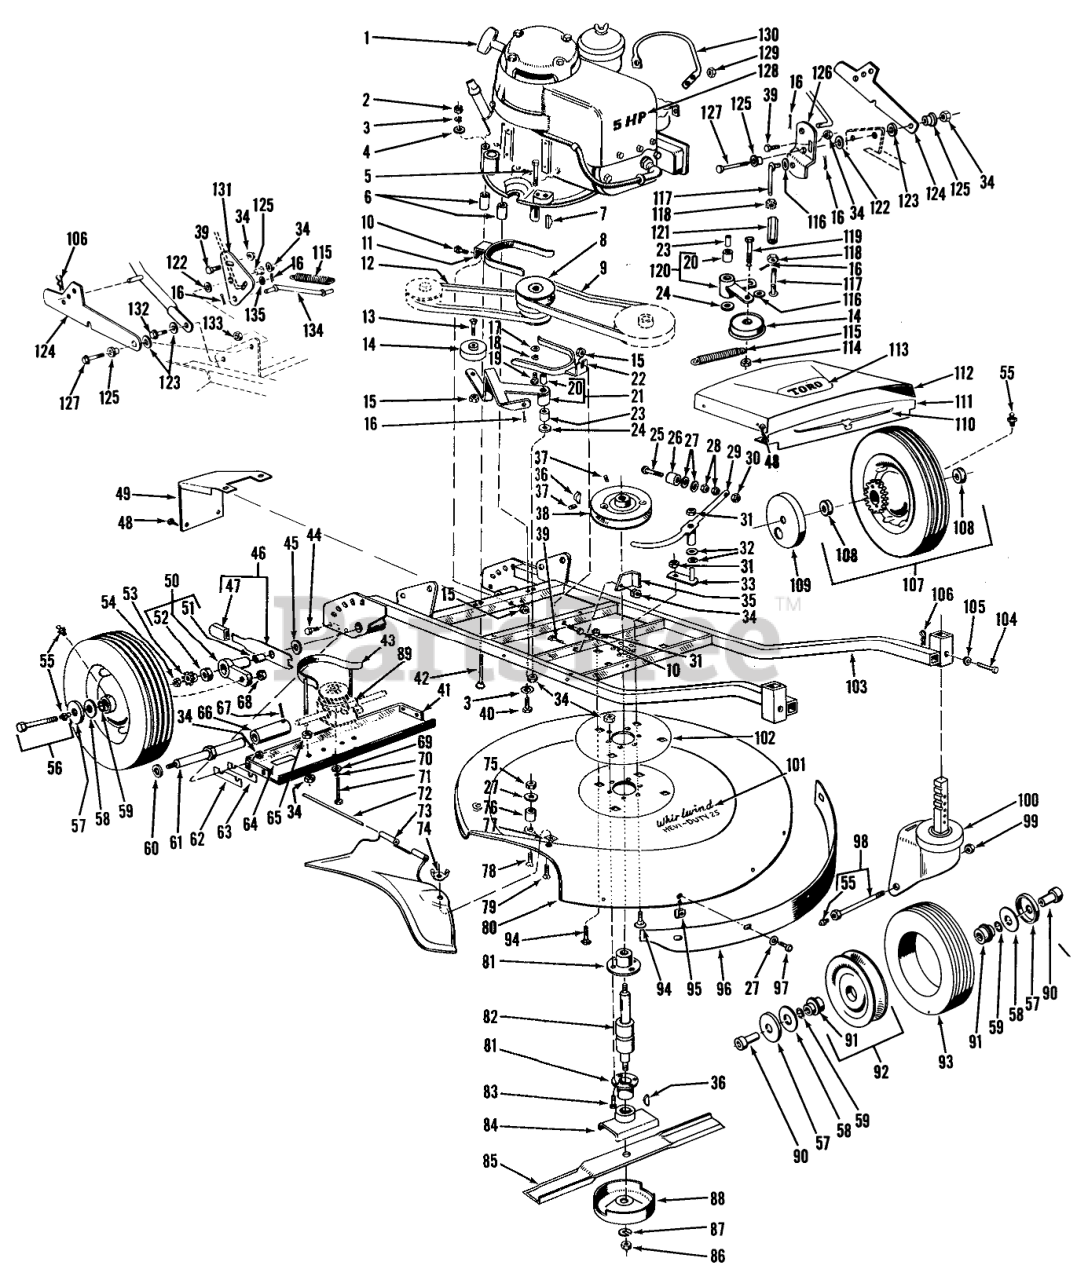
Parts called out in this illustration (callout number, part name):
1	Engine
2	NUT-HEX
3	WASHER-LOCK
4	WASHER-PLAIN
5	SCREW-HH
6	Spacer
7	KEY-WOODRUFF
8	Pulley
9	CUTTER BELT
10	SCREW-HH
11	Retainer, Belt
13	Flat Head Screw
14	PULLEY B
15	NUT-LOCK, NI
16	PIN-COTTER
17	WASHER-FLAT
18	WASHER-LOCK
19	SCREW-HH
20	BUSHING
21	Idler Arm
22	Retainer Belt
23	ENGINE PIVOT SPACER
24	SPACER
25	10-24X1-1/2 RND HD MS
26	BUMPER
27	WASHER-FLAT
28	NUT-HEX
29	Arm, Brake
30	NUT-LOCK, NI
31	NUT-LOCK, NI
32	WASHER-FLAT
33	Base Pivot
34	NUT-LOCK, NI
35	Belt Retainer
36	KEY-WOODRUFF
37	SCREW-HSH
38	CUTTER PULLEY
39	SCREW-HH
40	SCREW-HH
41	Support
42	Screw, Truss Head
43	Belt Band
44	SCREW-HH
45	WASHER
46	Spring Arm
48	10-16 X 3/8 THDG SCREW
49	Rear Shroud
50	Pivot Arm
51	.375 RPP BALL BEARING
52	BUSHING
53	Pinion Kit
54	NUT-HJ
55	FITTING-GREASE
56	Axle Bolt Use on Serial No. 1 thru 250
57	SLINGER
58	Washer
59	O-RING
60	Washer
61	Drive Spindle
62	Shim .015
63	Shim .030
64	Serial & Patent No. Decal
65	NUT-JAM
66	Clutch Assembly
67	Groove Pin
68	NUT-LOCK, NI
69	WASHER-FLAT
70	WASHER-LOCK
71	SCREW-HH
72	Hinge Pin
73	DEFLECTOR
74	Nut Wing
75	NUT-HEX
76	Spacer
77	Nut, Speed
78	Screw
79	5/16-18X7/8 FLT HD MS
80	Housing
81	BEARING HOUSING
82	Bearing Spindle
83	SCREW-HH
84	Retainer
85	Blade
86	NUT-HEX
87	WASHER-LOCK
89	Transmission Assembly
90	Spacer
91	BEARING-BALL
92	Wheel W.A. w/Ref. No. 53
93	1.75-8 SEMIPNEU TIRE
94	BOLT-CARR
95	SPEED NUT
96	Cover
97	SCREW-HH
98	Axle Bolt w/Zerk
99	NUT-LOCK, NI
100	Caster
101	Decal
102	Plate
103	Frame
105	Grommet
106	PIN-COTTER
107	Rear Wheel Assy. (Includes item 108)
108	BEARING-BALL
109	Wheel Cover
110	Decal
111	Shroud Panel
112	Shroud, Front
113	Decal
114	NUT-LOCK
115	EXTENSION SPRING
116	WASHER
118	NUT-KEPS
119	Screw
120	Idler Arm
121	CONTROL ROD SLEEVE
122	Washer
123	SPACER
124	Latch
125	PIVOT
126	Bellcrank, Cutter
127	SCREW-HWH, THREAD CUT
128	Decal
129	NUT-LOCK
131	Bellcrank
132	Screw
133	NUT-LOCK, NI
135	Spacer
